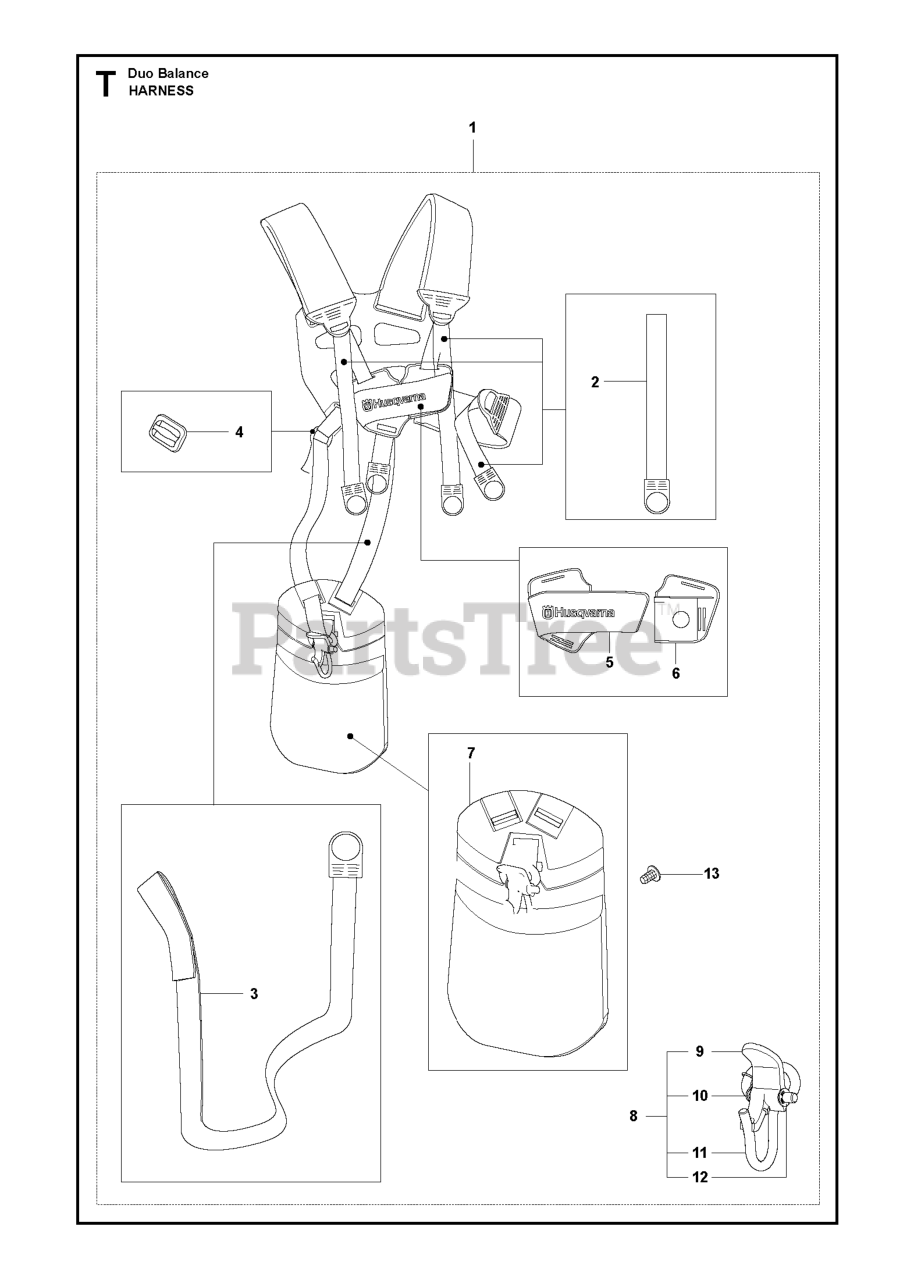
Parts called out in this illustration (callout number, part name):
1	Duo-Bal Harness
1	Harness
4	RP CLIP
5	FRONT PIECE
6	FRONT PIECE
8	HARNESS HOOK, COMPLETE
9	CATCH *
10	SPRING
11	HOOK
